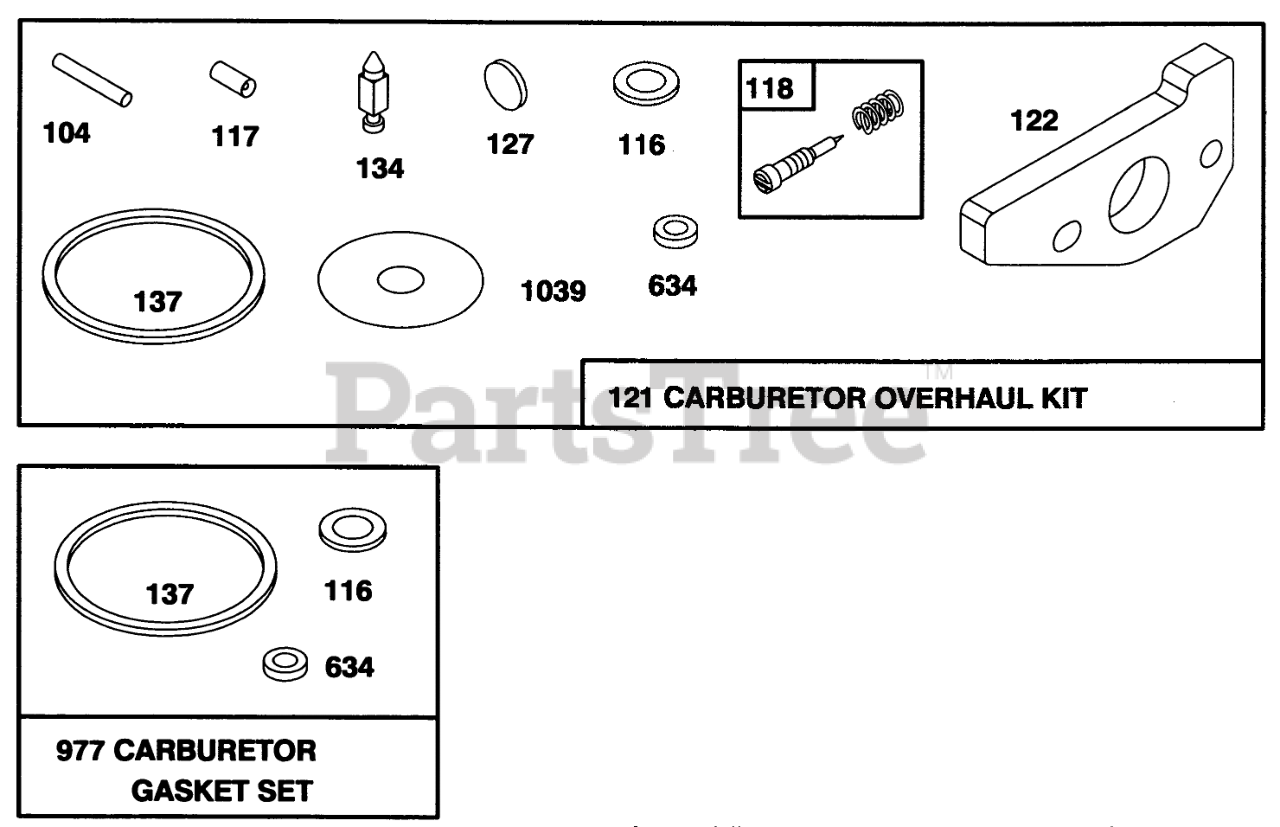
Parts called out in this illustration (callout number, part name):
104	FLOAT HINGE PIN
116	SEALING GASKET
118	VALVE KIT - NEEDLE
121	CARBURATOR OVERHAUL KIT
122	ADAPTER ASSEMBLY
134	Valve-Float (Includes Seat)
137	FLOAT BOWL GASKET
358	GASKET SET
634	SEAL WASHER
977	CARBURATOR GASKET SET
1039	FLOAT LIMITER
